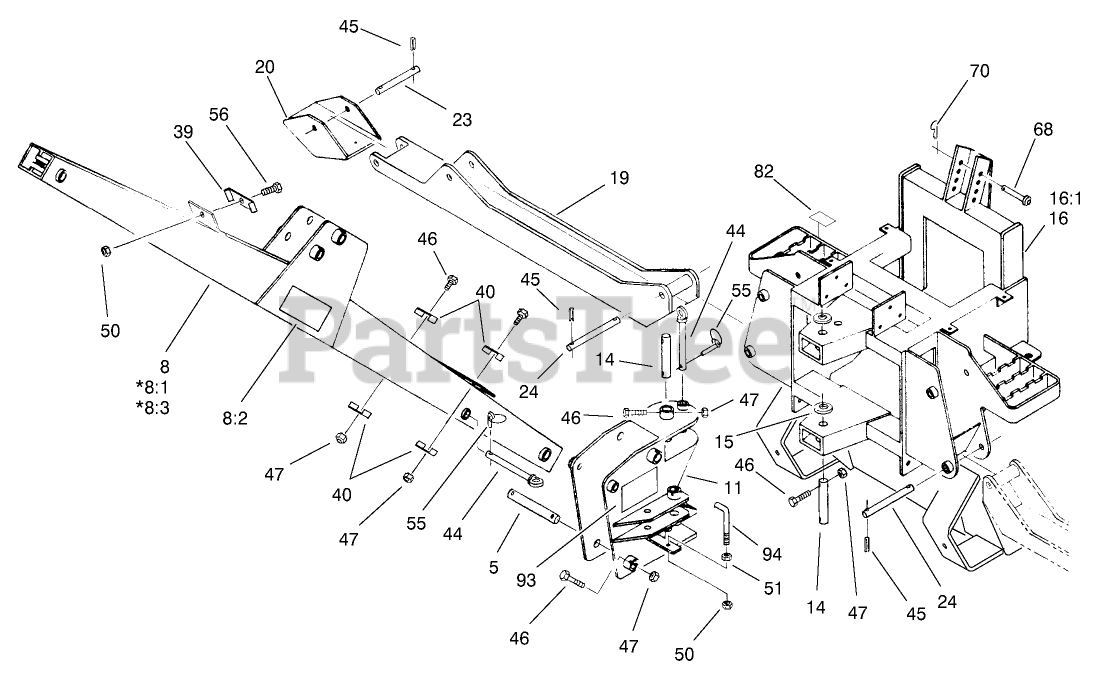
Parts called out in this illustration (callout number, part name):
5	PIN-BUCKET
8	BOOM ASM
8:2	DECAL-WARNING
11	SWIVEL ASM
14	PIN-PIVOT
15	WASHER-THRUST
16	BOX FRAME ASM
19	STABILIZER ASM
20	STABILIZER FOOT ASM
23	PIN-FOOT, STABILIZER
24	PIN-STABILIZER
39	BRACKET-HOSE
40	BRACKET-HOSE
44	LOCK PIN ASM
45	PIN-ROLL
46	SCREW-HH
47	NUT-LOCK
50	NUT-LOCK, NI
51	NUT-HEX
55	PIN-LYNCH
56	SCREW-HH
68	PIN-CLEVIS
70	PIN-HAIR
82	DECAL-WARNING
93	DECAL-PLACEMENT, PIN
94	BRACKET-HOSE
